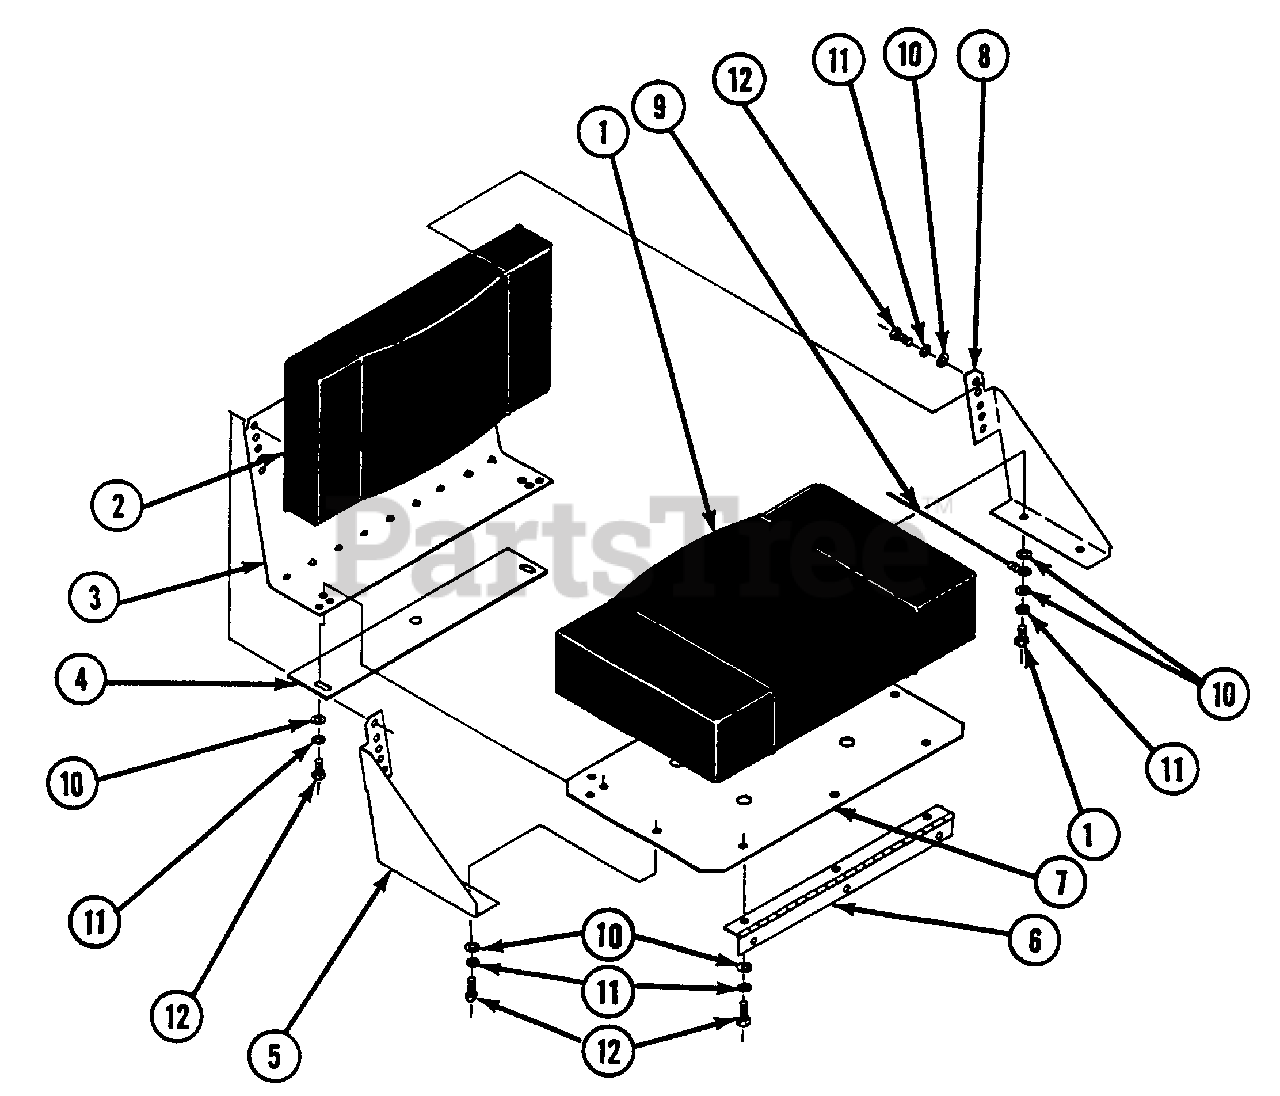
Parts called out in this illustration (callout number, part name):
1	SEAT CUSHION ASSEMBLY
2	BACK CUSHION ASSEMBLY
3	BACK REST SUPPORT
4	ACTUATOR WLDT.
5	SEAT BACK BRACKETS RIGHT
6	SEAT HINGE
7	BOTTOM, SEAT SUPPORT
8	SEAT BACK BRACKETS LEFT
9	CABLE ASSEMBLY, SEAT
10	WASHER, 5/16 STD. FLAT
11	LOCKWASHER, 5/16 STD. SPLIT SPRING
12	CAPSCREW, HEX. 5/16-18 X 1, GR. 5
